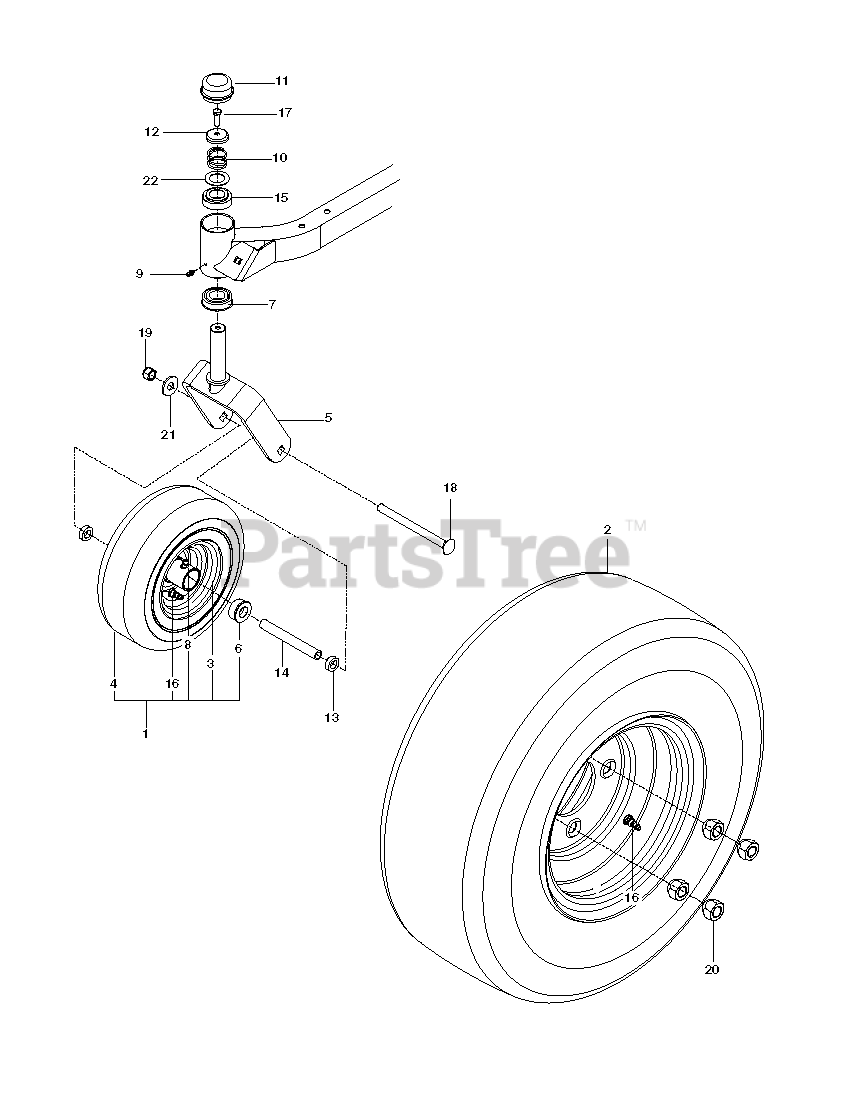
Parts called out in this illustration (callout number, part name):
1	TIRE, CASTER, COMPLETE
2	TIRE ASM 18 X 8.5-8
4	TIRE, 4. 10-5.4 PLY
5	CASTER DK BLUE
6	BUSHING, WHEEL, 3/4"
7	BEARING FLANGED
8	ZERK
9	ZERK, 3/16, DRIVE IN
10	SPRING, CASTER
11	GREASE CAP
12	CASTER.PLUG
13	SPACER, 5/16"
15	BUSHING, CASTER
16	VALVE STEM TR-412
17	5/16-18X1 HHB G5W/NY
18	RHSNB 1/2-13 X 6.50 GR2 ZD
19	NUT 1/2-13 HEX CNTRLK GR 5 ZD
20	LUG NUT 1/2F
21	WASH USS FLAT 1/2
22	WASHER, 1.025 ID X 1.64
